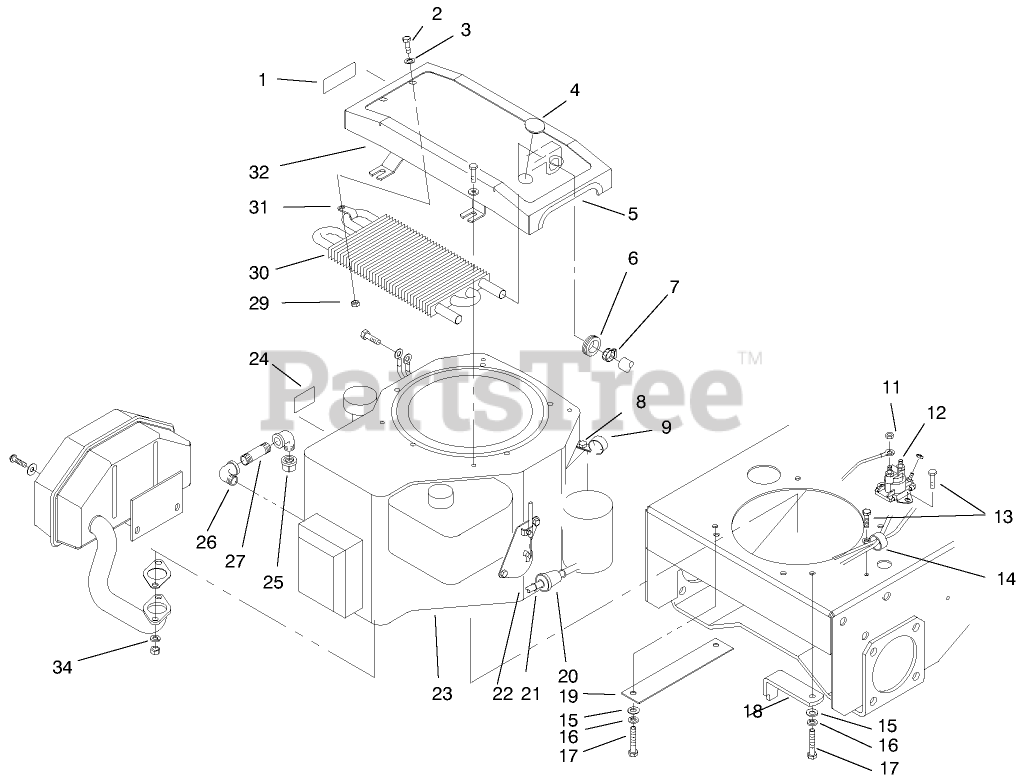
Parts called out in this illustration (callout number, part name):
1	DECAL-SHUT OFF, FUEL
2	WASHER-FLAT
3	SCREW-HH
4	PLUG-PLASTIC
5	TRIM-MOUNT, COOLER
6	GROMMET
7	CLAMP-HOSE
8	SCREW-HWHTF
9	CLAMP-R
11	NUT-KEPS
12	Solenoid
13	SCREW-HWH
14	CLAMP-R
15	WASHER-PLAIN
16	WASHER-LOCK
17	SCREW-HH
18	RETAINER-CLUTCH
19	GUARD-PULLEY
20	FILTER-FUEL
21	CLAMP-HOSE
22	HOSE-FUEL
23	Engine-15 Hp Kohler
24	DECAL-SURFACE, HOT
25	CAP-PIPE
26	ELBOW-STREET, 90 DEG
27	NIPPLE
29	NUT-LOCK, NI
30	Cooler-Oil
31	CLAMP-R
32	MOUNT-COOLER
